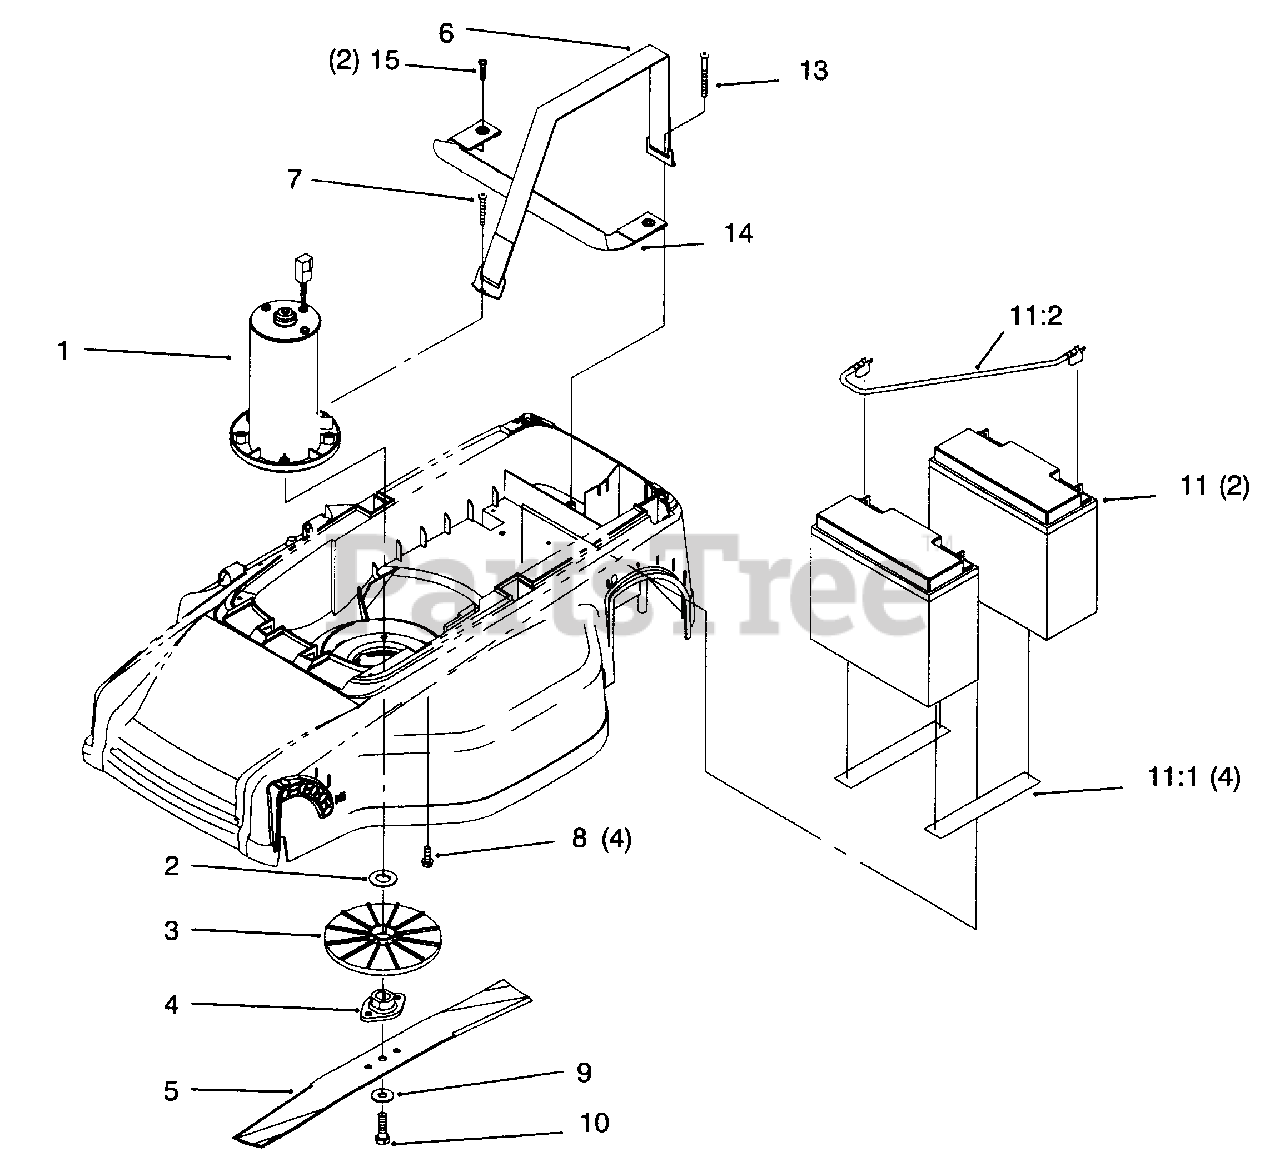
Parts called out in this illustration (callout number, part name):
1	ASM-Motor 24V
5	Blade
6	ASM-Strap
7	Screw-PPH
8	Screw-HWH
9	Washer-Spring
10	Bolt-Blade
11	Battery Set
11:1	Tape-Foam
11:2	ASM-Wire Battery
13	Screw-PPH
14	Strap-Battery 24v
